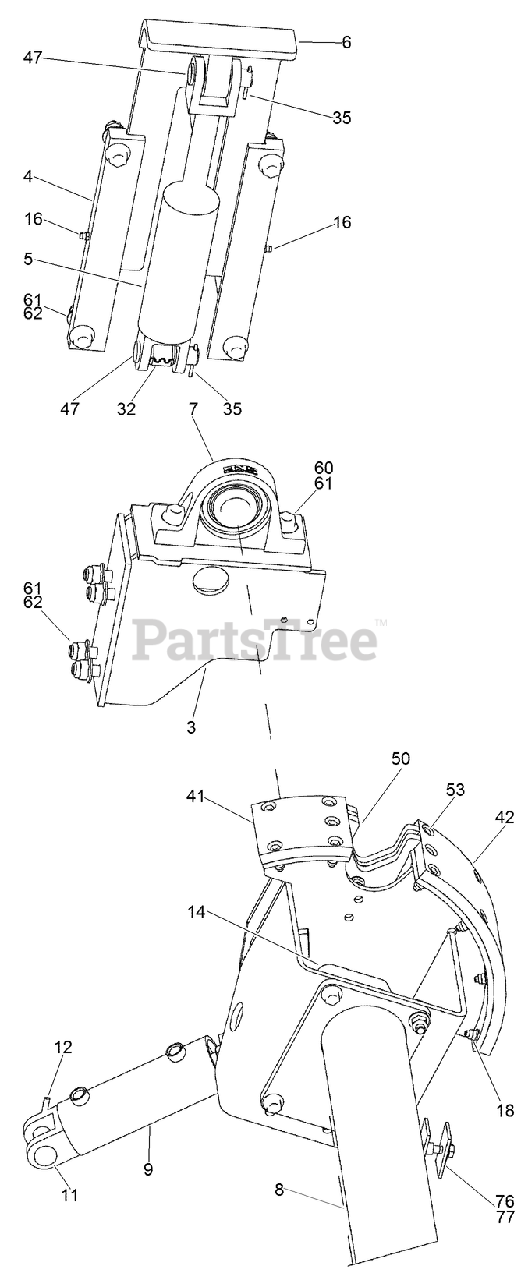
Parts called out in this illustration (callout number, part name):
3	ASSEMBLY - Bearing Mount
4	PLATE - Elevator Guide
5	HYD CYLINDER ASM
6	ASSEMBLY - Elevator
7	BEARING-PILLOW
8	ASSEMBLY - Cam
9	HYD CYLINDER ASM
11	PIN - Clevis
12	PIN-COTTER
14	PLATE - Spacer
16	FITTING-Lube 1/4-28 Tpr SAE-LT .54 Long
18	NUT, METRIC FLANGE PREVAILING - M6 Zinc
32	BUSHING-SPRING
35	PIN-Cotter, 1/8 x 1-1/4 in ZN
41	PAD-WEAR, ROD LOADER
42	PAD-WEAR, ROD LOADER
47	PIN-CLEVIS
50	PLATE-GUIDE, PIPE
53	SCREW, METRIC FLANGE w/BODY-M6 x 25
60	SCREW-HHF
61	NUT-HHF, LOCK
62	SCREW-HFH
76	PLATE-COVER, TWIN
77	BOLT-Hex, 5/16 NC x 1-1/4 inch
